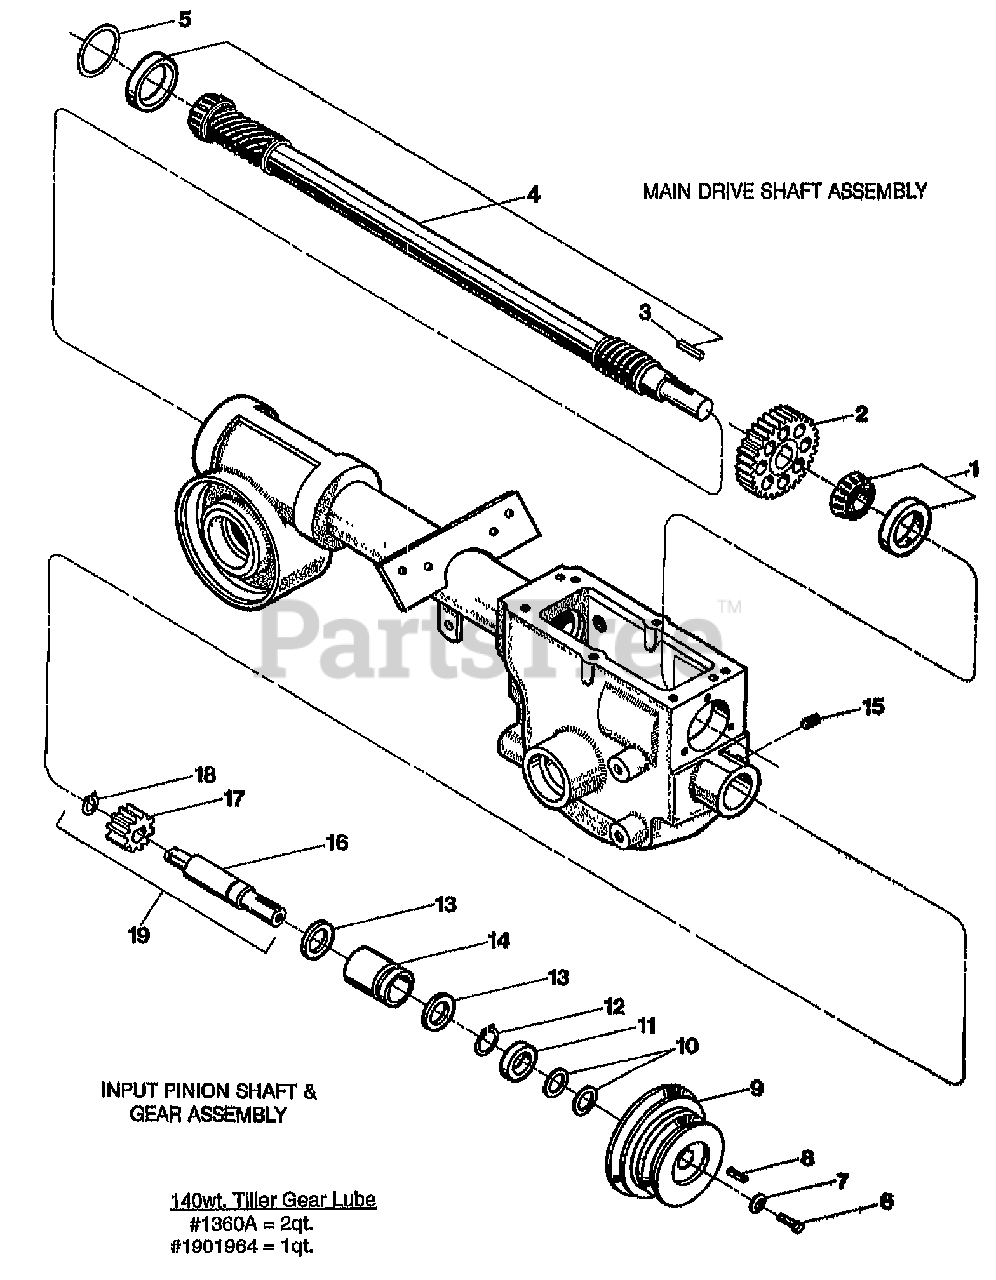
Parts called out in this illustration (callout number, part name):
1	KIT-BRG CONE & RACE-DRIVESHAFT
2	GEAR-SPUR 30 TEETH
3	KEY-.188 SQX1.0
4	KIT-DRIVESHAFT
5	SHIM-1.75X1.5X.01
5	SHIM-1.75X1.5X.03
5	SHIM-1.75X1.5X.005
6	SCR-HH 5/16-24X.75 G5 ZP
7	WASHER-.827X.331X.098 (disc spring, concave surface faces pulley)
8	KEY-.188 SQX1.0
9	PULLEY-TRANS MACH (Trans. drive pulley, 2 grooves 1 for ea.: forward & reverse.)
10	WASHER # .875 X .65 X .06
11	SEAL-PINION SHAFT PT/85030/00
12	RING-RETAIN EXT .707 ID
13	WASHER-1.022X.752X .059
14	BUSHING-1.24X.75X1.8 GRVD
15	SCR-SS 5/16-18X.375
16	SHAFT-PINION(P-V)
17	GEAR-PINION P/M
18	RING-BOWED EXT .461 ID
19	PINION W/GEAR&SNAP RING (Inc. #16-18)
